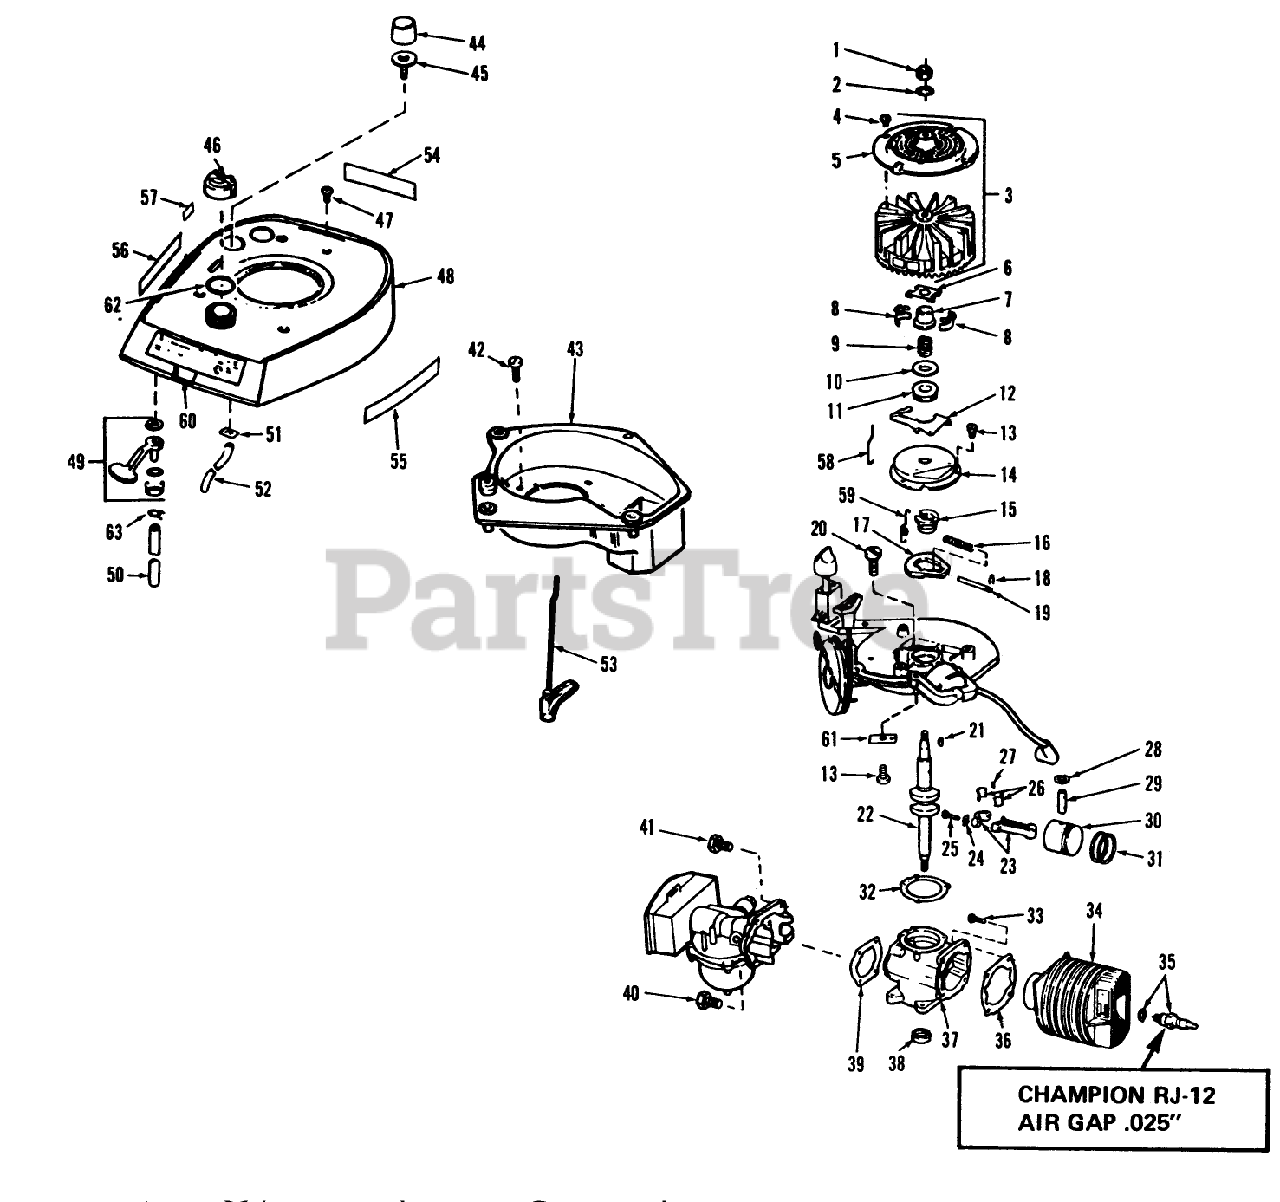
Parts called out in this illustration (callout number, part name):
4	SCREW F
7	COLLAR S
9	SPRING S
11	THRUST COLLAR S
12	LEVER-GOVERNOR S
13	SCREW S
14	DUST COVER S
15	SPARK ADV. S
16	SPARK ADV. SPRING S
17	FLYWEIGHT S
18	SPARK ADJ. SPRING
19	PIN,SPARK ADV. S
26	LINER ASM
28	RING-RETAINING
32	GASKET S
35	Spark Plug Gasket RJ-12
36	GASKET S
39	GASKET S
40	SCREW S
41	SCREW S
47	SCREW S
51	LOCKNUT S
53	KNOB & ROD AY. S
57	Decal-Fingertip
60	SPRING BAR
62	GASKET S
